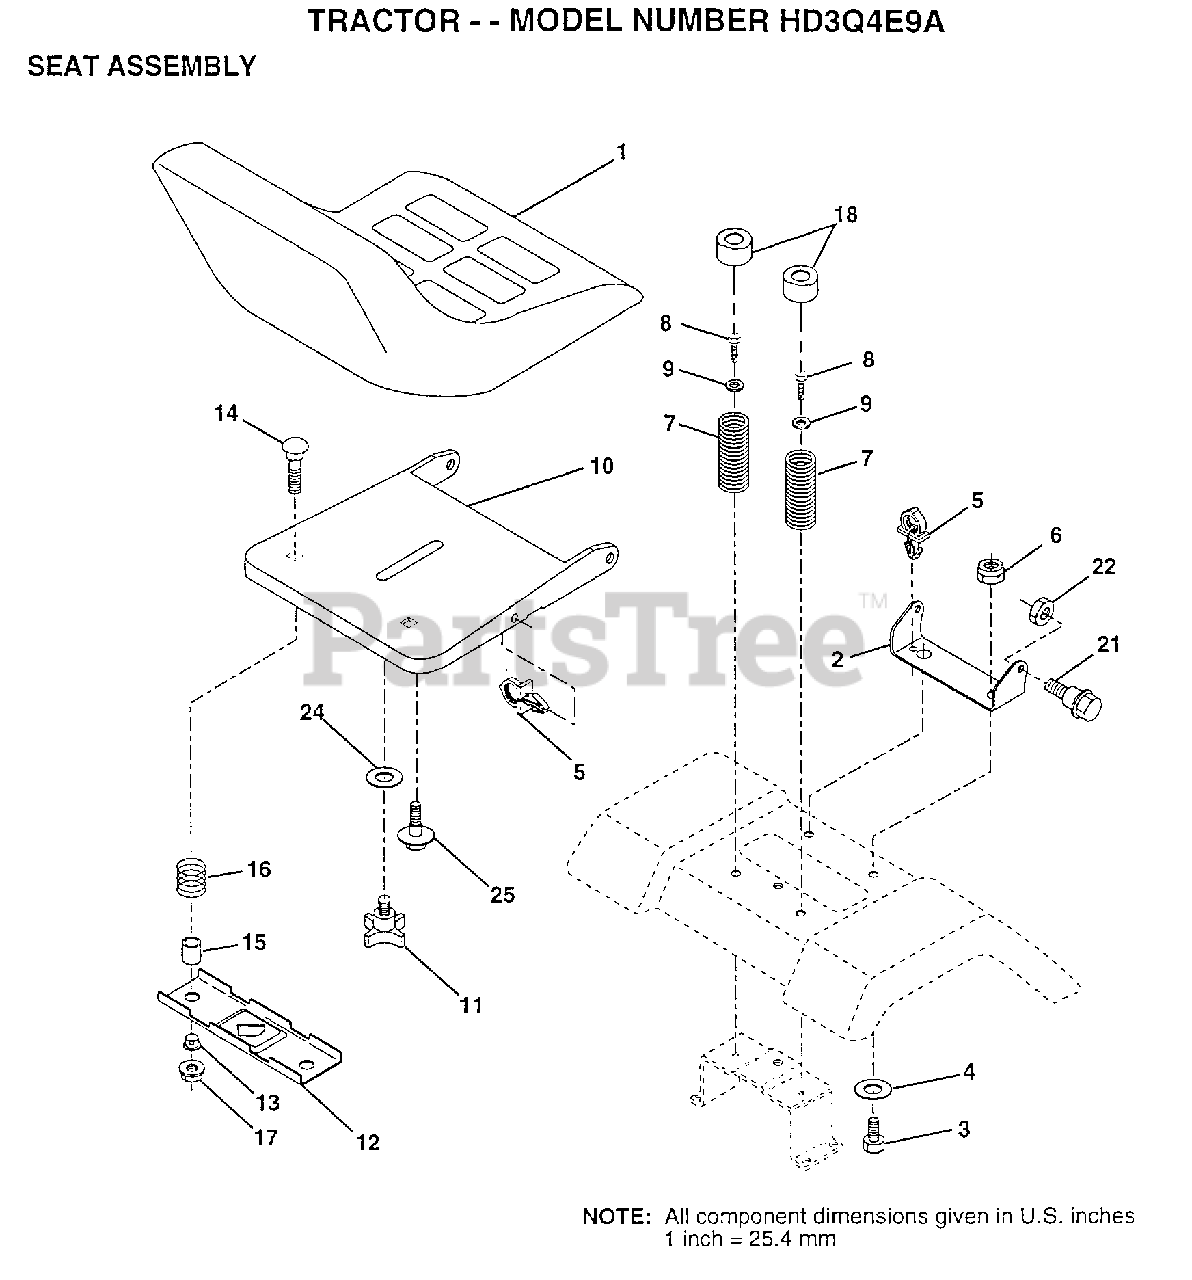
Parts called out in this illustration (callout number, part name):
1	SEAT.2500/1516.BK
2	BRACKET PVT SEAT
3	BOLT
4	WASHER PM
5	CLIP.PUSH-IN.HING
6	NUT
7	SPRING COMPRESSIO
8	SCREW GTV
9	WASHER
11	"KNOB 1/2"" YT"
12	BRKT SWITCH
13	BUSHING
15	SPACER SPLIT
16	SPRING COMPRESSED
18	CAP SPRING
21	BOLT.SHLD.5/16-18
24	WASHER
25	"BOLT,SHOULDER"
